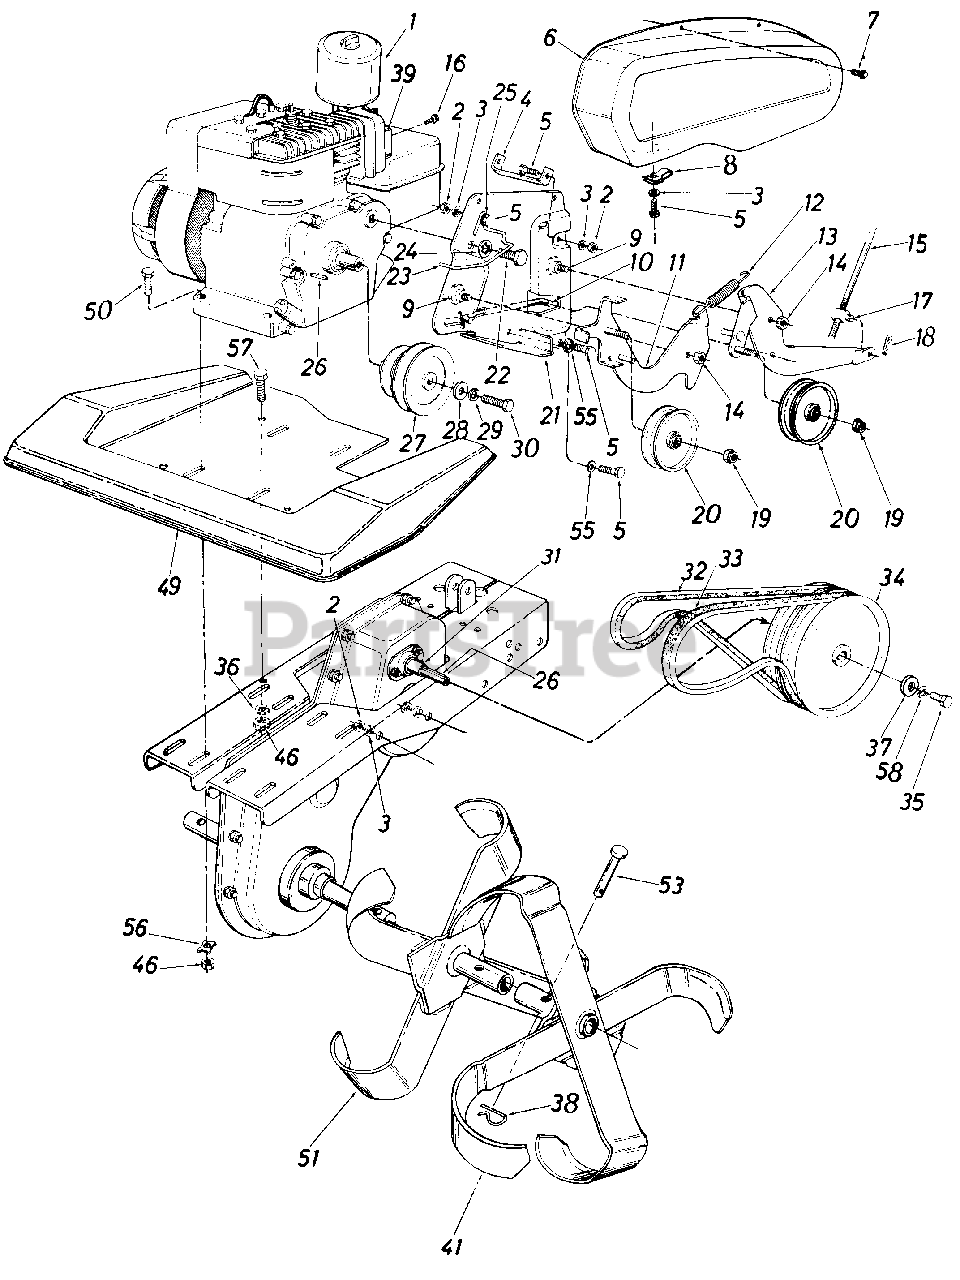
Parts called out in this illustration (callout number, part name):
1	Engine
2	Hex Nut 1/4-20 Thd.
3	L-Wash. 1/4" I.D.
4	Support Bracket
5	Hex Bolt 1/4-20 x .75" Lg.
8	"U"-Type Speed Nut
9	Shoulder Bolt .625" Dia. x .170" Lg.
10	Control Rod
11	Reverse Idler Brk't. Ass'y.
12	Spring Idler Brk't.
13	Forward Idler Brk't. Ass'y.
14	Hex Cent. L-Nut 3/8-16 Thd.
15	Clutch Control Rod
16	Hex Self-Tap Scr. #8-32 x .38" Lg.
17	Ferru le
18	Inter. Cotter Pin
19	Hex Jam Nut 3/8-24 Thd.
20	Fl-Idler w/Flanges 3.12 O.D. x .75
21	Clutch Mounting Plate
22	Hex Bolt 1/2-20 x .75 Spec.
23	Belt Guard Rod
24	Internal L-Wash. 1/2" I.D.
25	Fl-Wash. 1/4" I.D.
26	Sq. Key 3/16" x 1.50" Lg.
27	Engine Pulley
28	Fl-Wash. 3/8" I.D. x 1.00"
29	L-Wash 3/8" I.D.
30	Hex Bolt 3/8-24 x 1.25" Lg.
31	Spacer .635 I.D. x .88 O.D. x 1.035 Lg.
32	"V"-Belt 1/2" x 41" Lg. Reverse
33	"V"-Belt 1/2" x 37" Lg. Forward
34	Chain Case Pulley 6.0" Dia.
35	Hex L-Bolt 5/16-18 x 1.0" Lg.
36	Shake-Proof Wash.
37	Fl-Wash. 5/16" I.D. x 1.120
38	Internal Cotter Pin 1/2" Dia.
41	See Tine Chart
46	Hex Nut 5/16-18 Thd.
51	See Tine Chart
55	Bell-Wash.
56	Shake-Proof Wash.
57	Hex Bolt 5/16-18 x .75" Lg.
58	L-Wash. 5/16" I.D.
